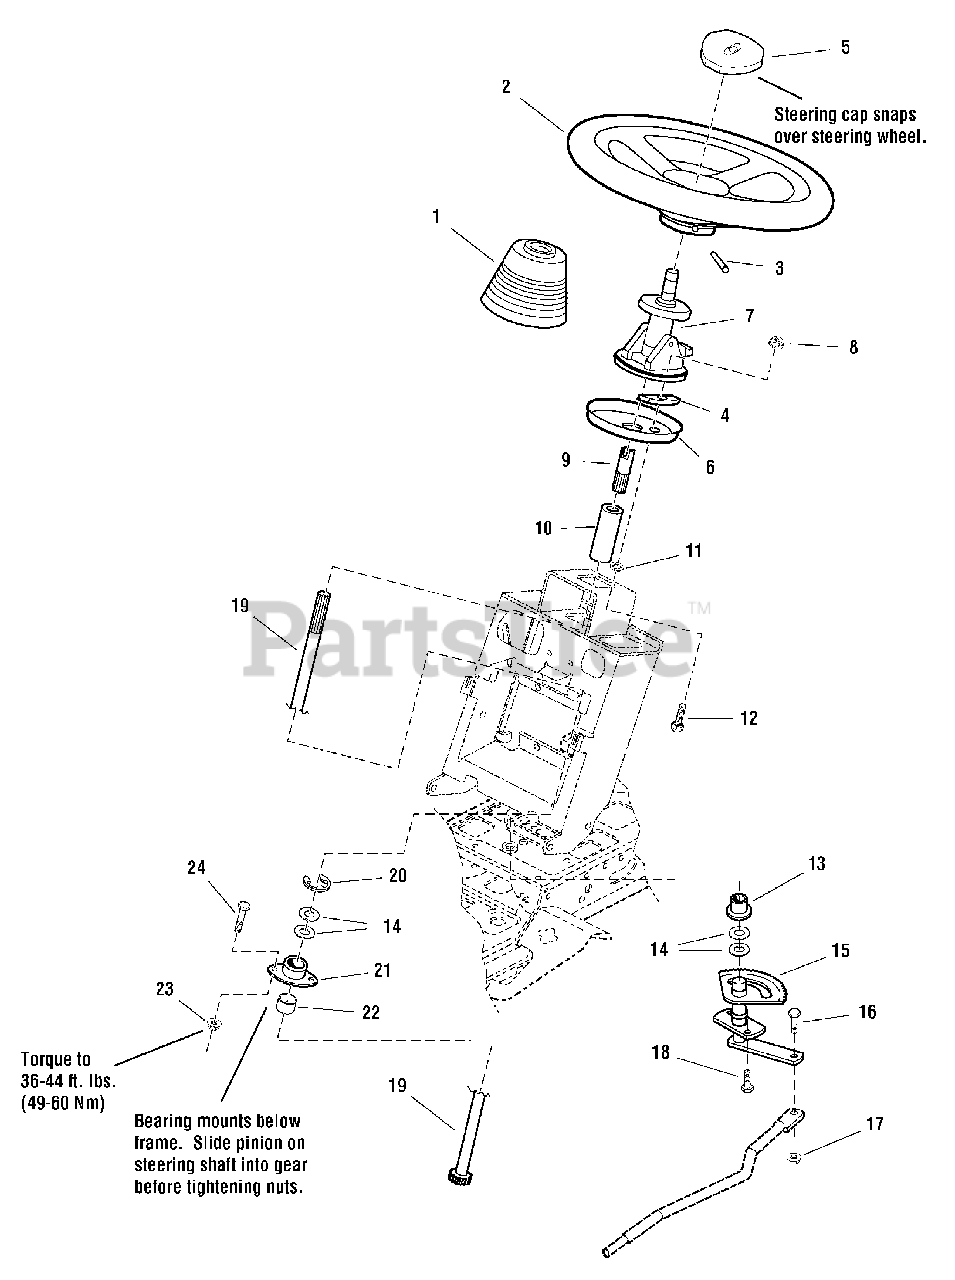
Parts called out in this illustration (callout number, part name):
1	BOOT, Tilt Steering Unit
2	STEERING WHEEL, Straight Shaft
5	CAP, Steering Wheel, Simplicity
5	CAP, Steering Wheel, Plain
6	MOUNTING PLATE
7	TILT STEERING UNIT, Straight Shaft
8	NUT, Hex KEPS, 5/16-18
9	ADAPTER, Tilt Steering Splined
10	COUPLER, Splined Steering Manual with Tilt
11	NUT, Push
12	CARRIAGE BOLT, 5/16-18 x 1
13	BUSHING, Nylon
14	WASHER, 3/4
15	GEAR &, Shaft ASSEMBLY, Steering
16	CAPSCREW, Hex Thin Head, 3/8-16 x 1-3/4
17	NUT, Hex Flange Two-Way Lock, 3/8-16
18	CAPSCREW, Hex Washer Head Taptite, 5/16-18 x 3/4
19	SHAFT & PINION ASSEMBLY, Steering Manual Tilt
20	RING, Clipring Extension
21	BEARING, 3/4 x 1-11/16, 3" Long
22	SPACER, 3/8" Long
23	NUT, Hex Flange Whiz Lock, 3/8-16, Small
24	CAPSCREW, Hex Head Flange Whiz Lock, 3/8-16 x 3/4, Black
